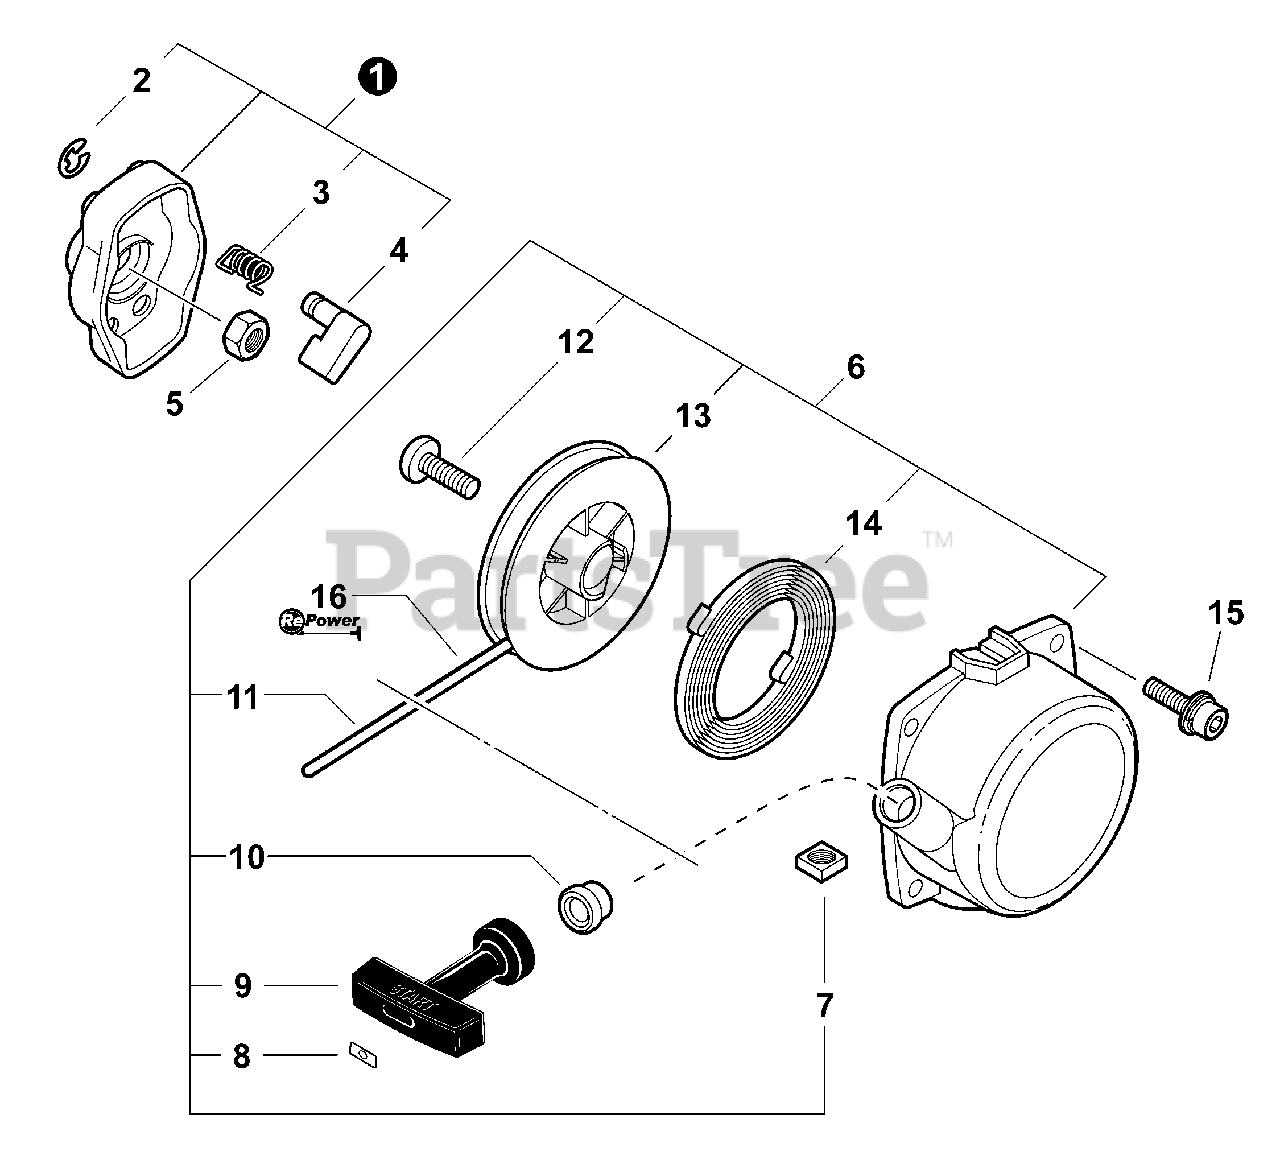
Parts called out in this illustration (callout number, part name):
1	STARTER PAWL ASY
2	RING, RETAINING - 4
3	SPRING, RETURN
4	PAWL, STARTER
6	STARTER ASY
7	NUT - 5 -- SQUARE
8	RETAINER, ROPE
9	GRIP, STARTER
10	GUIDE, ROPE
11	ROPE, STARTER - 3.5×850
13	REEL, ROPE
14	SPRING, REWIND
15	SCREW - 4×14
16	ROPE, STARTER - REPOWER BULK
